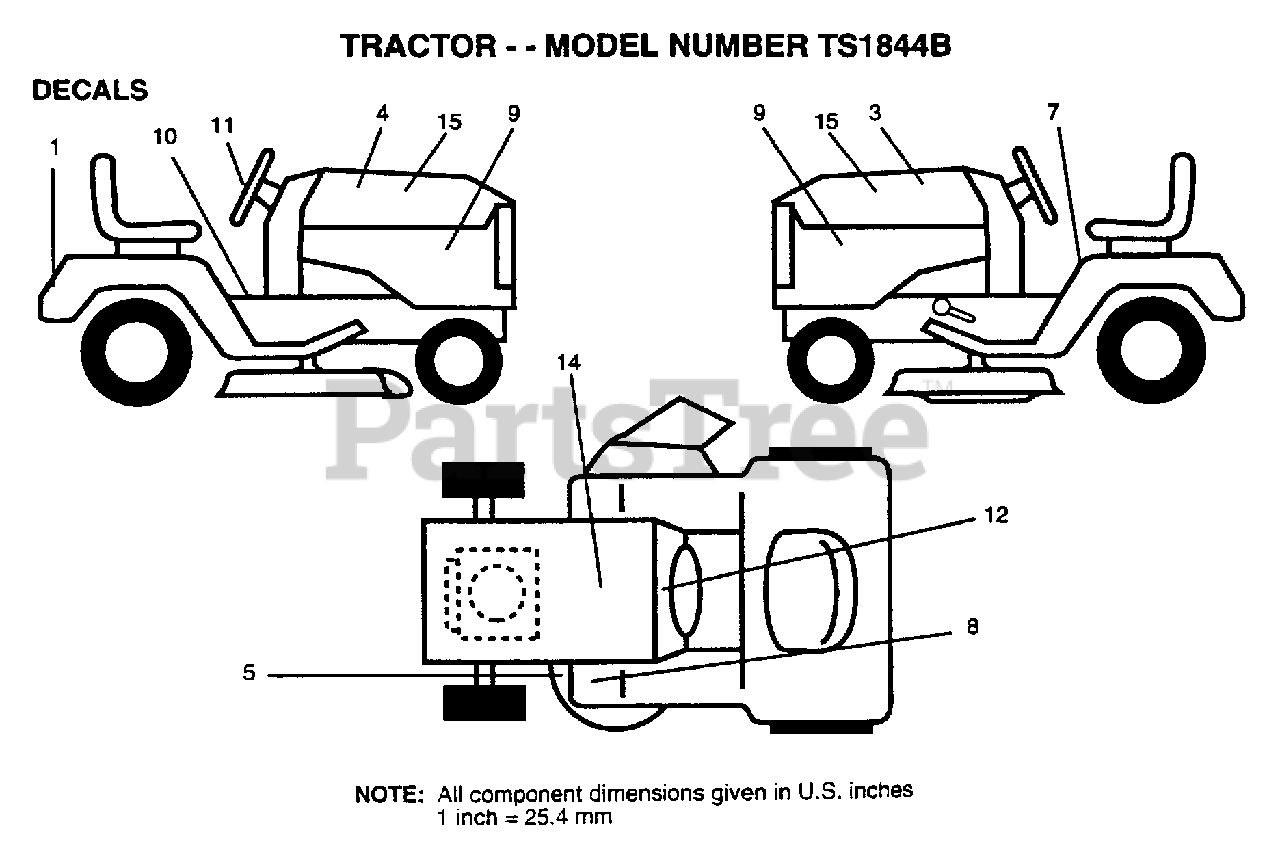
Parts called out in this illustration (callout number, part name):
1	DECAL.FEND.YT/GT
3	DECAL, HOOD LH
4	DECAL, HOOD RH
5	"DECAL.V.BELT.44"""
7	DECAL
9	DECAL, SIDE PANEL
10	DECAL BRAK PARK
11	DECAL.INS.WHL.STG
12	DECAL.DASH.INST.
14	DECAL
15	NAMEPLATE.HUSK.LG
